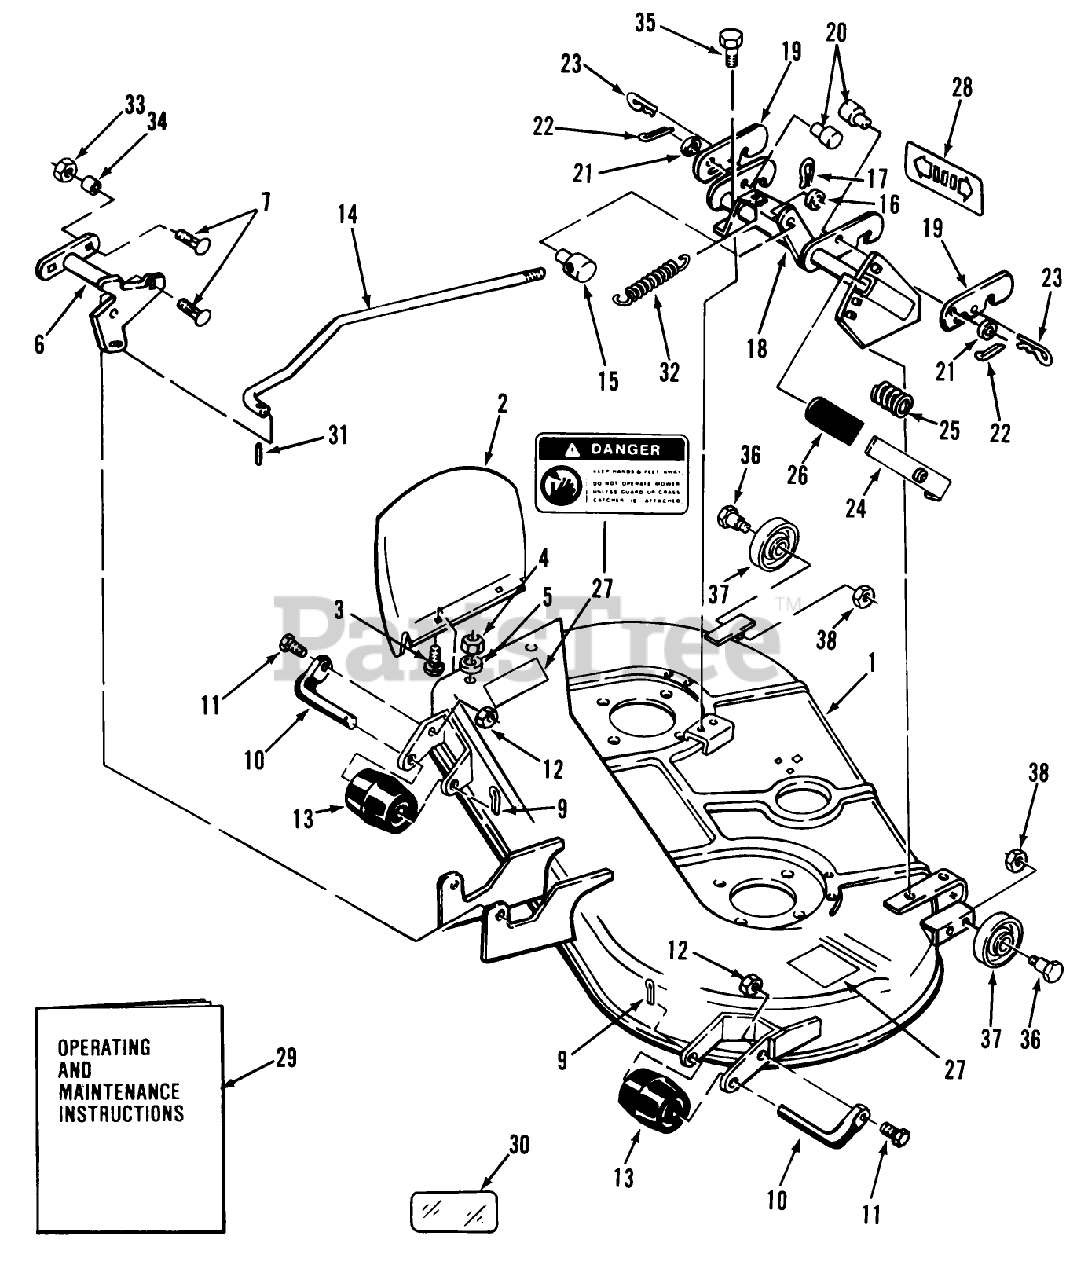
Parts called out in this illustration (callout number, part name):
1	Deck-Mower
2	Chute Extension
3	Bolt
4	Nut
5	Collar
6	Lift Arm
7	Bolt-Carriage
9	Cotter Pin
10	ROLLER-SHAFT
11	Bolt
12	Nut
13	Roller
14	ASS'Y-HEIGHT ADJ R
15	STUD-TRUNION
16	Washer
17	Hairpin Cotter
18	ASS'Y-HEIGHT ADJ R
19	Latch
21	Washer
22	Cotter Pin
23	Hairpin Cotter
24	LEVER ASSY
25	SPRING-COMPRESSION
27	Danger Decal
28	DECAL-HOC
29	Operating and Maintenance Instructions
30	DECAL-OVERLAY
31	SPIROL PIN
32	SPRING-EXTENSION
33	LOCKNUT-FLANGE
34	SPACER
35	Bolt
36	BOLT-SHOULDER
37	WHEEL-GAGE
38	NUT
